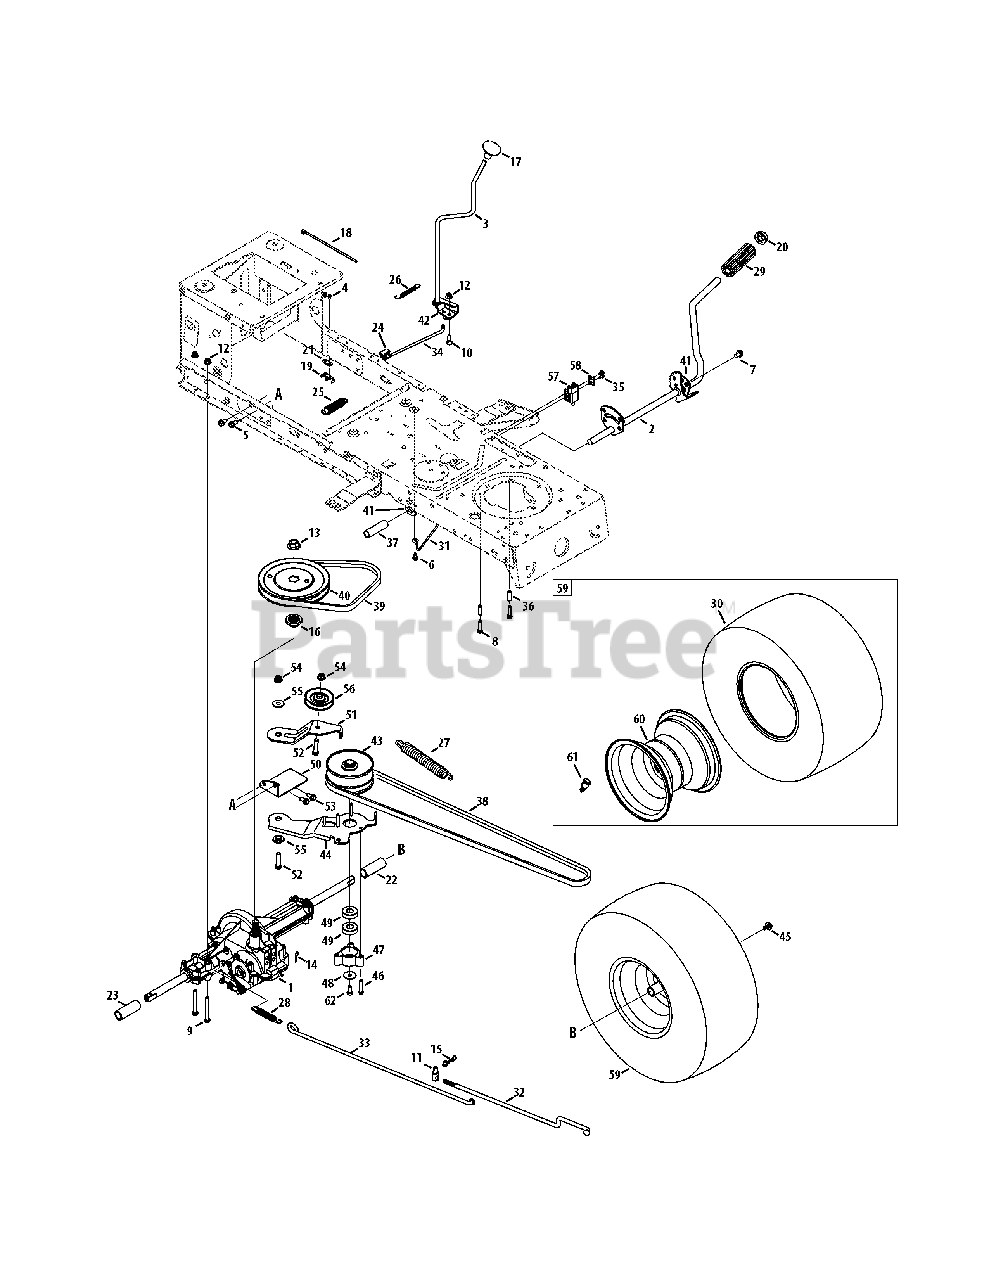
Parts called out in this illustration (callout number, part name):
1	Transmission Drive Assembly
2	Pedal Assembly
3	Shaft Lever Assembly
4	Screw, 8-18:0.500
5	Screw, 5/16-18 x .750
6	Screw, 1/4-20 x 0.500
7	Screw, 5/16-18 x 0.625
8	Screw, 1/4-20 x 1.250
9	Hex Screw, 5/16-18 x 2.75
10	Hex Screw, 5/16-18 x .75
11	Ferrule, 3/8-24 X .375 DIA.
12	Flangelock Nut, 5/16-18
13	Flange Nut, 9/16-18
14	Cotter Pin INT- .125 DIA
15	Bow-Tie Cotter Pin
16	Pulley Hub, 5/8 SPLINE
17	Shift Knob
18	Cable Tie
19	Short Spring Switch
20	Push Cap, 5/8
21	Plate Insulator Nut
22	Sleeve, .758 x .821 x 3.3125
23	Sleeve, .758 x .821 x 2.4375
24	Shift Bearing Plate
25	Spring Extension, .80 OD x 3.28 LG
26	Spring Extension, .38 OD x 3.25 LG
27	Spring Extension, .94 OD x 6.75 LG
28	Spring Extension, .59 OD x 4.00 LG
29	Foot Pad, 4.0 LONG
30	Tire, 20 x 8 x 8 Rd. Sh.
31	Belt Keeper Rod
32	Variable Speed Control Rod
33	Brake Rod
34	Shift Rod
35	Shoulder Screw, #10-32 x .500
36	Spacer, .260 x .375 x 1.030 Lg.
37	Spacer, .640 ID x .76 OD x 2.63
38	V Belt, 5L: 70.90 Poly
39	V Belt, 5L: 35.25 Poly
40	Trans. Pulley
41	Pedal Support Bracket
42	Shaft Adjust Bracket
43	Variable Speed Pulley Assembly
44	Bracket Assembly
45	SEMS Screw, 5/16-24 x .750
46	Screw, 1/4-20 x 1.500
47	Bearing Cup
48	Flat Washer, .330 x 1.25 x .06:HT
49	Ball Bearing, 17 x 40 x 12
50	Transmission Bracket Assembly
51	Idler Bracket Assembly
52	Hex Screw, 3/8-16 x 1.75
53	Screw, 5/16-18 x 0.750
54	Flange Lock Nut, 3/8-16
55	Shoulder Spacer, .625 ID x .169
56	Idler Pulley
57	Switch Interlock
58	Plate Switch
59	Wheel Assembly, 20 x 8 x 8
60	Rim Assembly
61	Valve Stem
62	Hex Screw, 5/16-24 x .750
